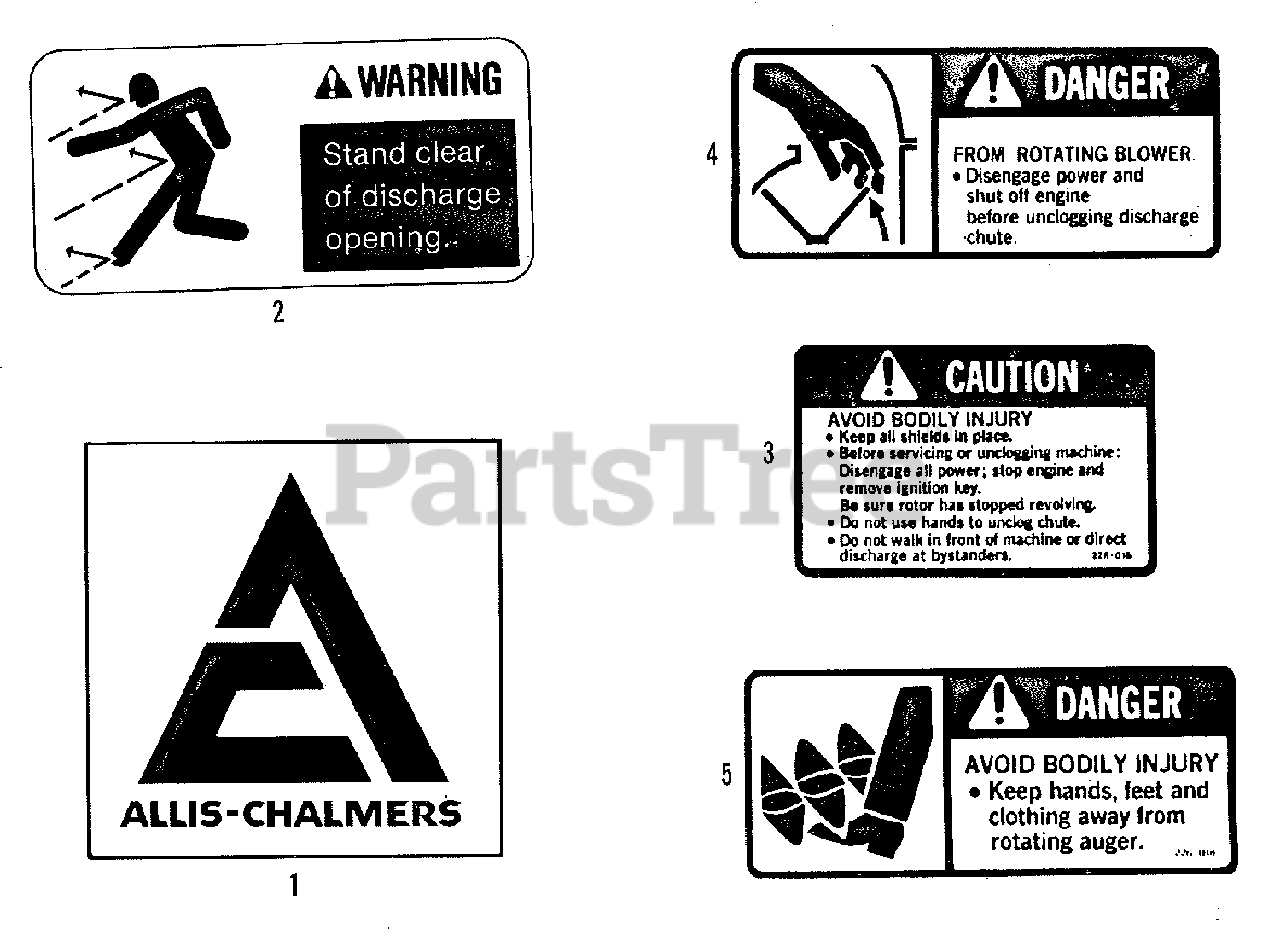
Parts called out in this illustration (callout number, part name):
1	DECAL, Allis-Chalmers
2	DECAL, Warning (Stand Clear of Discharge Opening)
3	DECAL, Caution (Avoid Bodily Injury - Keep All Shields in Place)
4	DECAL, Danger (From Rotating Blower)
5	DECAL, Danger (Avoid Bodily Injury - Keep Hands, Feet, Etc.)
